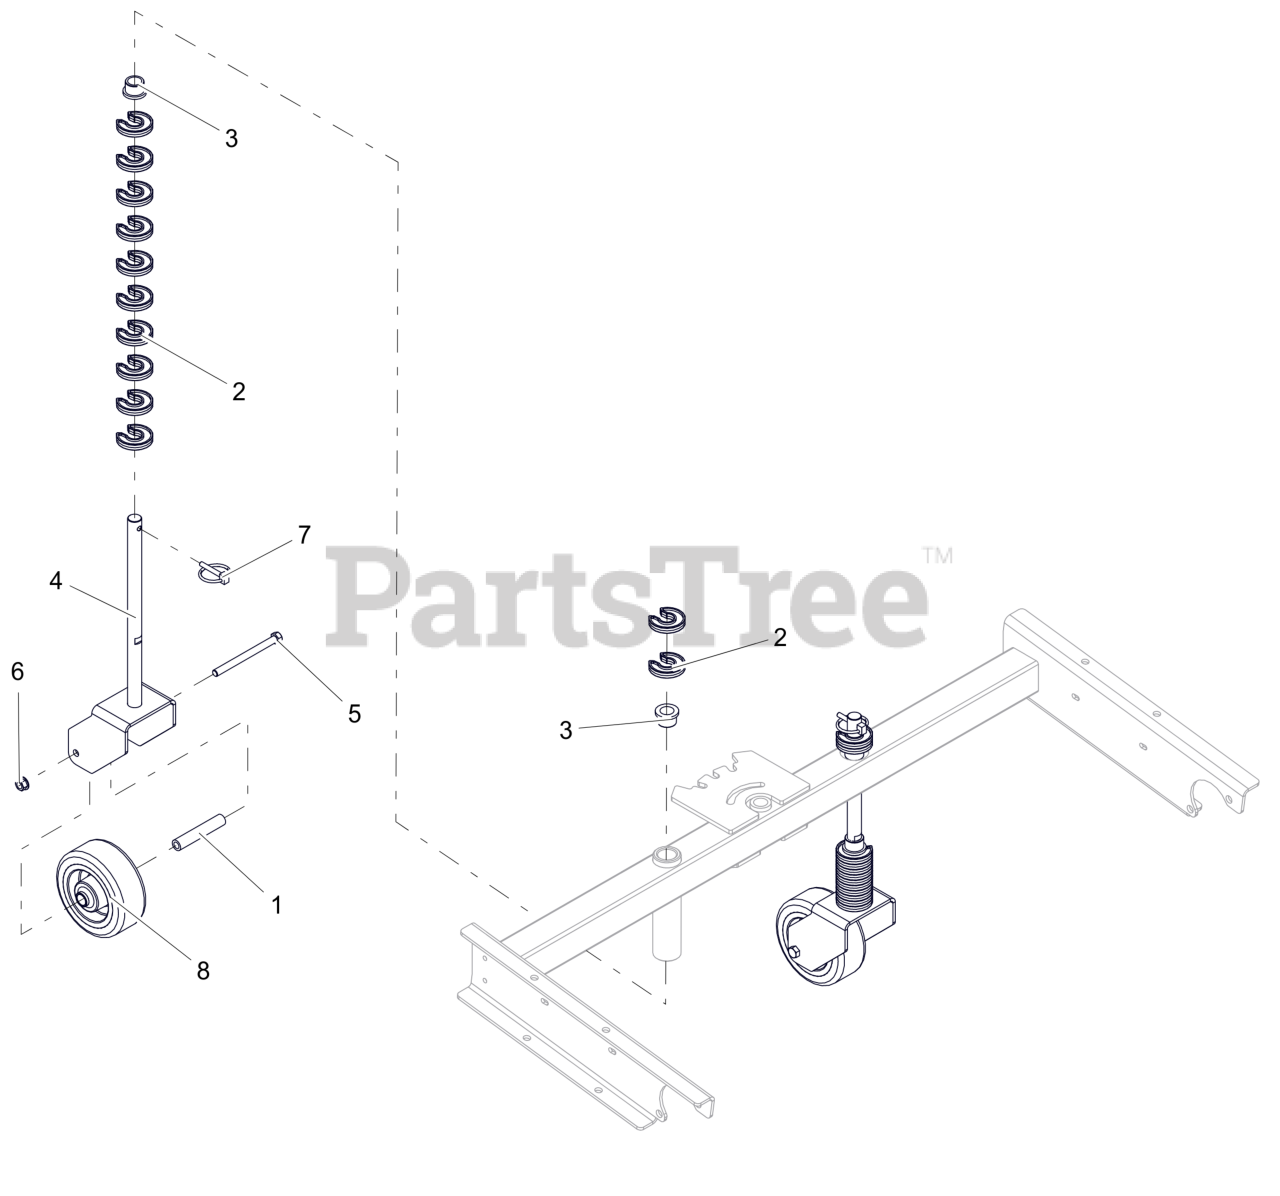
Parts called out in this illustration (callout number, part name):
1	SPACER, CASTER WHEEL
2	CLIP-HOC FIXED
3	BUSHING, FLANGE .75X.75X1.0
4	FORK, CASTER
5	BLT, HEX 0.375-16X4.5 GR5 ZCC
6	NUT-LK-TOP-FLG .38-16 ZC120
7	PIN, LYNCH .25X1.562 ZCC
8	WHEEL, CASTER - 5"OD
